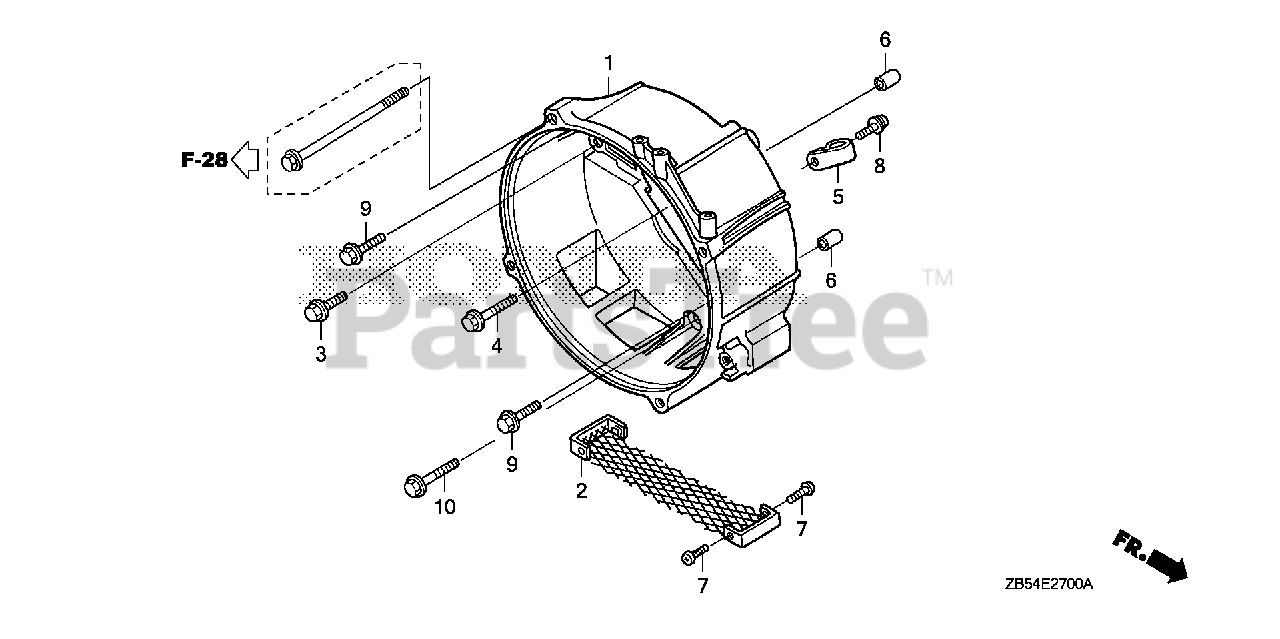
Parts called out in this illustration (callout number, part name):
1	HOUSING, FR.
2	COVER, GENERATOR DUCT
3	BOLT, FLANGE (8X32)
4	BOLT, FLANGE (8X40)
4	BOLT, FLANGE (8X40) Use up to Engine SN 1003236.
5	CLIP (18.6MM)
6	PIN A, DOWEL (10X14)
7	SCREW, PAN (5X16)
8	SCREW-WASHER (5X12)
9	BOLT, FLANGE (8X32)
10	BOLT, FLANGE (8X40) Use up to Engine SN 1003236.
10	BOLT, FLANGE (8X40)
